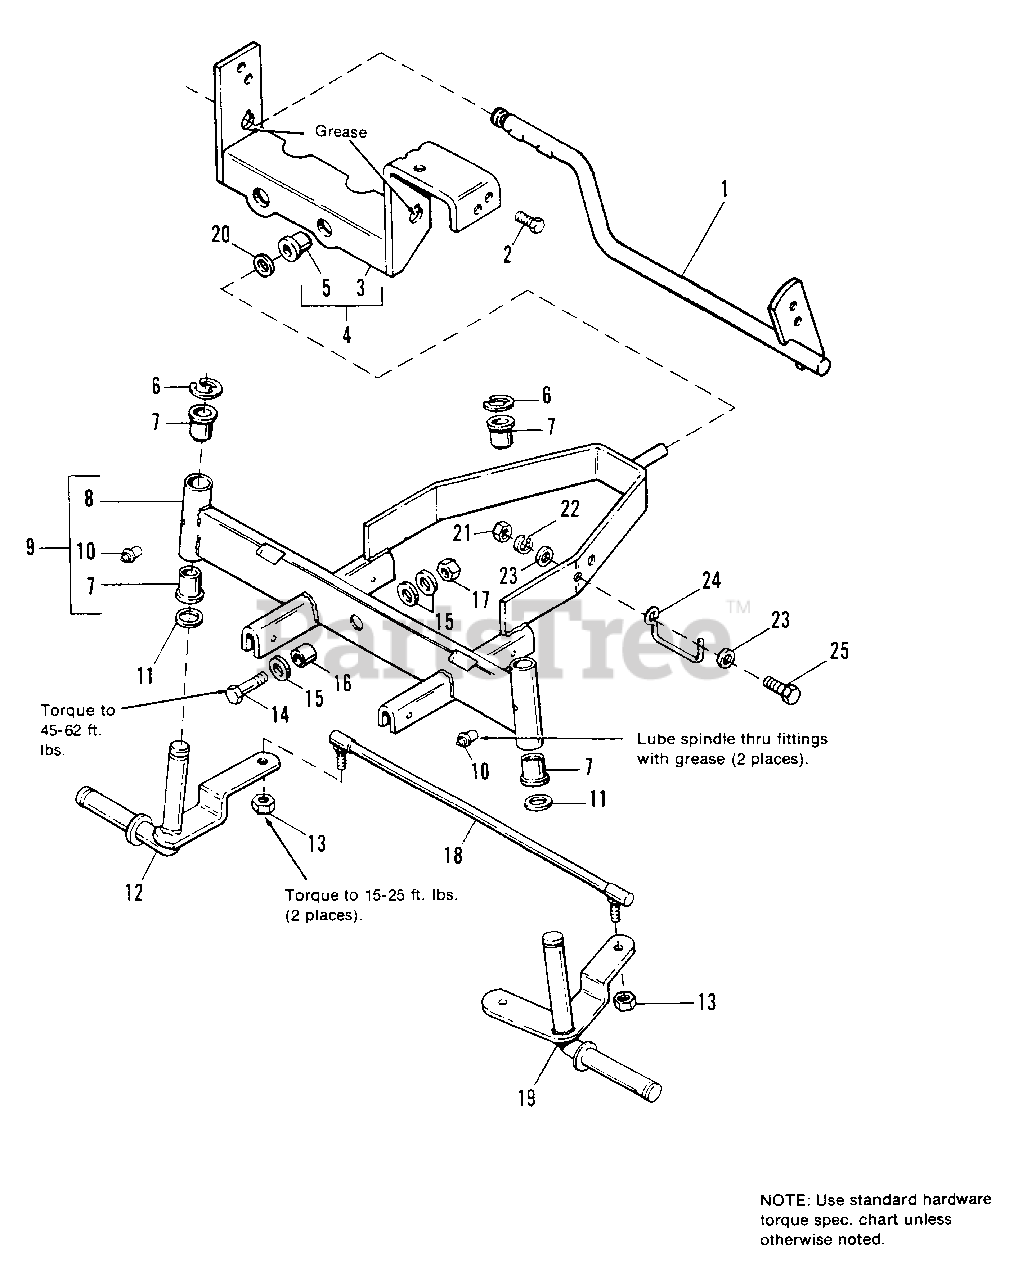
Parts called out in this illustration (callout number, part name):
1	LEVER ASSY., Brake
2	SCREW, Taptite, 5/16-18 x 3/4
4	SUPPORT ASSY., Rear w/Bushing (Includes Ref. No. 3 & 5)
6	"E" RING, Ext. 3/4
9	AXLE ASSY., Front (Includes Ref. No. 7, 8 & 10)
10	FITTING, Lube, Drive Type
11	WASHER
12	SPINDLE ASSY. R.H.
13	LOCKNUT, Hex, 3/8-24, Gr. 8
14	CAPSCREW, Hex, 1/2-13 x 1-3/4, Gr. 8
15	WASHER, 9/16
16	SPACER
17	LOCKNUT, Hex, 1/2-13
18	TIE ROD ASSY.
19	SPINDLE ASSY., L.H.
20	WASHER, 5/8
21	NUT, Hex, 5/16-18
22	LOCKWASHER, 5/16
23	WASHER, 5/16
24	GUIDE, Drag Link
25	CAPSCREW, Hex Hd., 5/16-18 x 1
